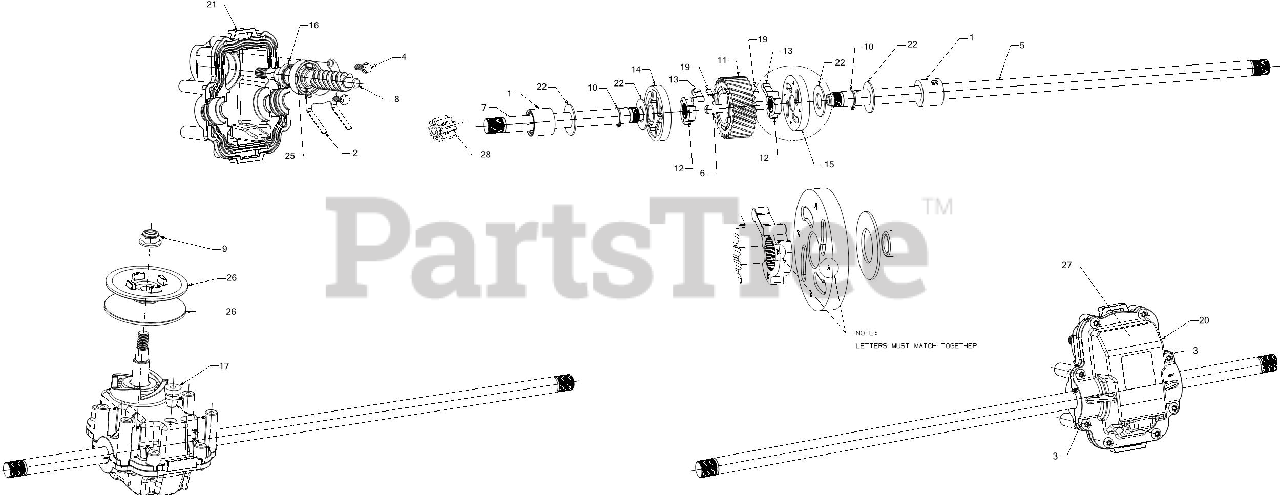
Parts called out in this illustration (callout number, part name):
1	BEARING ASSEMBLY
2	SPRING PLATE
3	SCREW .159 X .610
4	SCREW .159 X .43
5	AXLE SHAFT (RH)
6	PIN
7	AXLE SHAFT (LH)
8	WORM SHAFT
9	FLANGE LOCK NUT 5/16-18
10	SNAP RING FOR .500
11	HELICAL GEAR
12	HUB
13	DRIVE ARM
14	DRAG PLATE (LH)
15	DRAG PLATE (RH)
17	OIL PLUG
18	THREE BOND SEALANT
19	MAGNET
20	LOWER HOUSING
21	UPPER HOUSING
22	FLAT WASHER .508X1.000X.040
23	TRANSMISSION OIL
24	GREASE
25	BALL BEARING
26	HALF PULLEY 2.50 OD
27	TRANSMISSION COVER
28	SPUR GEAR 9T
